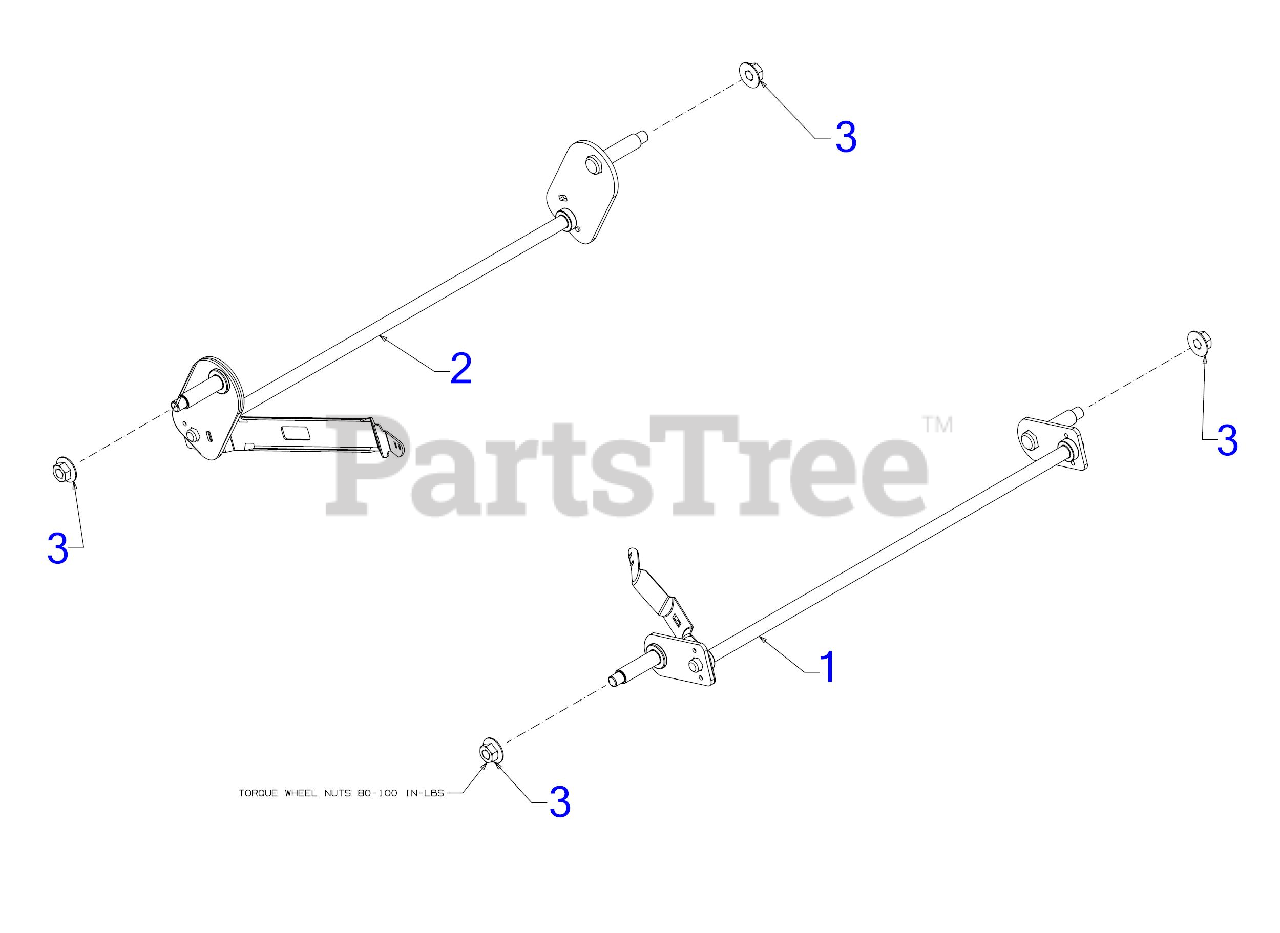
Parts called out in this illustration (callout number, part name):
1	7" FRONT AXLE ASSEMBLY
2	11" REAR AXLE ASSEMBLY
3	FLANGE LOCK NUT
